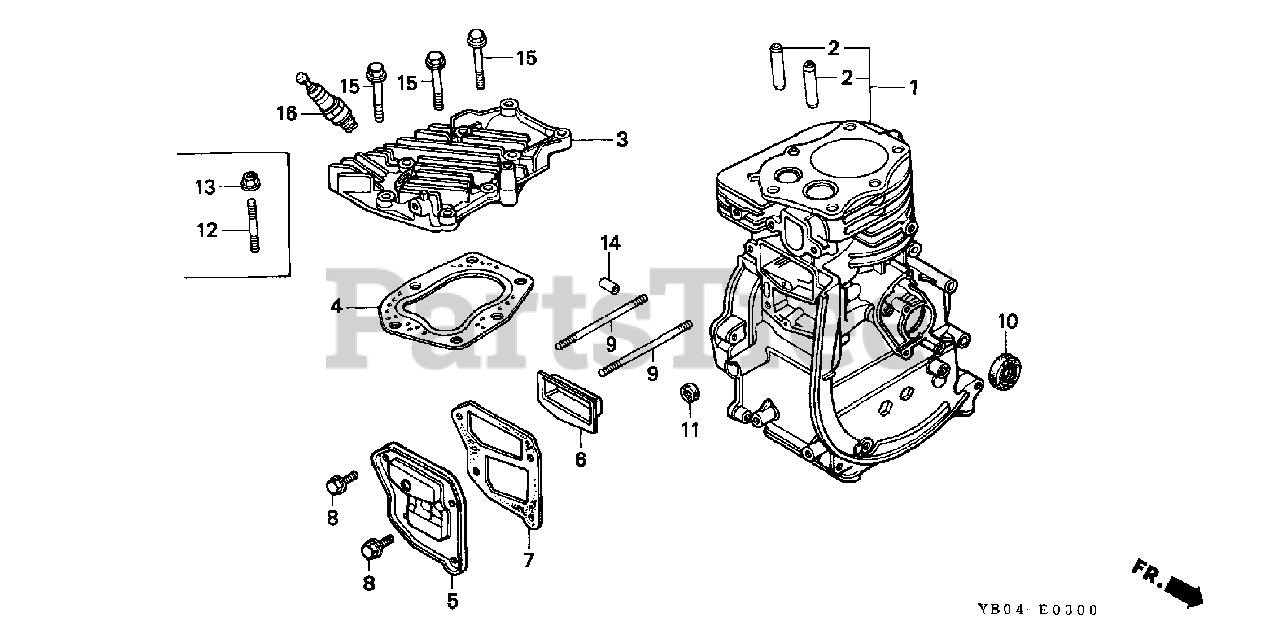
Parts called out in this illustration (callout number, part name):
2	GUIDE, VALVE (OS)
3	CYLINDER HEAD (NOT AVAILABLE)
4	GASKET, CYLINDER HEAD
5	COVER, TAPPET (NOT AVAILABLE)
6	SEPARATOR (INNER) (NOT AVAILABLE)
7	GASKET, TAPPET COVER
8	BOLT, FLANGE (5X10)
9	BOLT, STUD (5X80)
10	OIL SEAL (17X30X6) (NOK)
12	BOLT, STUD (6X45) (SOURCE: VINTAGE PARTS INC.)
13	NUT, FLANGE (6MM)
14	PIN A, DOWEL (8X14)
15	BOLT, FLANGE (6X35)
16	SPARK PLUG (BMR4A) (NGK)
16	SPARK PLUG (W14MR-U) (DENSO)
